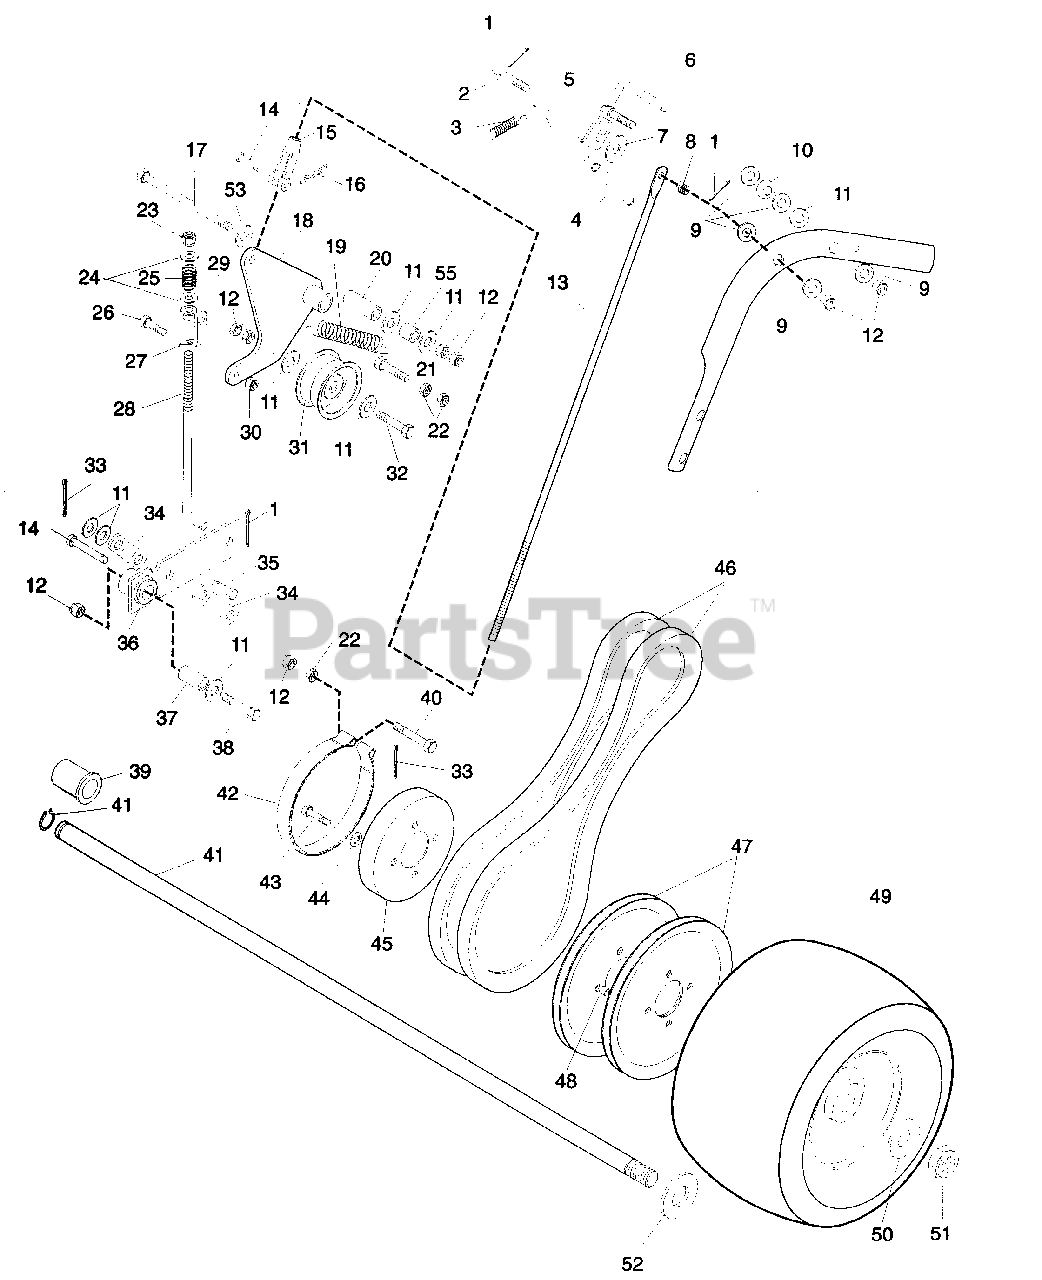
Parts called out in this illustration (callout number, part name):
1	Pin-Cotter .09 x .75 Extpsqct
2	Lever, Hand Control
3	Spring-Tension .041 x .500 x 1.750
4	Grip, Hand Clutch Lever
5	Weldment, Clutch-Brake Lock
6	Tip-Brake Lock Lever
7	Washer-Flat-Steel .4 x 1.375
8	Spring-Compression .045 x .600 x .750
9	Washer-Flat-Nylon .375 x .75 x .060
10	Spring Washer
11	Washer-Flat-Steel .406 x .812 x .065
12	Nut-Locking-Center .38-16
13	Rod, Clutch Actuating
14	Pin-Clevis .38 x 1.25
15	Clevis, .38-24 Adjustable
16	Pin-Hair Internal .08 x .18 x 1.18
17	Bolt-Hex .38-16 x 4.00 Grade 5
18	Weldment, Wheel Clutch Arm
19	Spring-Tension .069 x .62 x 3.50
20	Bushing, Sleeve .385 x .610 x 1.80
21	Bolt-Hex .38-16 x 1.50 Grade 5
22	Nut-Hex .31-18
23	Nut-Locking-Center .31-18
24	Washer-Flat-Steel .344 x .688 x .065
25	Spring-Compression .125 x .78 x 1.00
26	Bolt-Hex .25-20 x .75 Grade 5
27	Left-Bracket, Pro Brake Link
28	Rod, Brake
29	Bushing-Flange .320 x .620 x .312
30	Nut-Locking-Center .25-20
31	Sheave 3.25 x 1.25
32	Bolt-Hex .31-18 x 2.25
33	Pin-Cotter .12 x .75 Extprsqct
34	Link, Brake Arm
35	Pin-Clevis .38 x .75
36	Weldment, Brake Arm
37	Bushing, Sleeve .391 x .622 x .950
38	Bolt-Hex .38-16 x 2.00 Grade 5
39	Bushing-Flange 1.010 x 1.38 x 1.4 x 1.65
40	Ring-Retaining-External .906 x .078
41	Axle Shaft, Pro-150
42	Assembly, Brake Band, Pro
43	Bolt-Hex .31-18 x 1.50 Grade 5
44	Washer-Lock .31 x .078
45	Drum, Brake
46	Drive Belt, Matched Pair
47	Pulley-V 9.00 x 3.75
48	Bushing, Sleeve .385 x .625 x .475
49	Assembly, Wheel, 13 x 6.00-6
50	Washer-Flat-Steel 1.010 x 1.505 x .062
51	Nut-Locking-Center .44 -14
52	Washer-Thrust 1.55 x 1.002 x .093
53	Washer-Flat-Steel .38 x .87 x .179
54	Bushing
